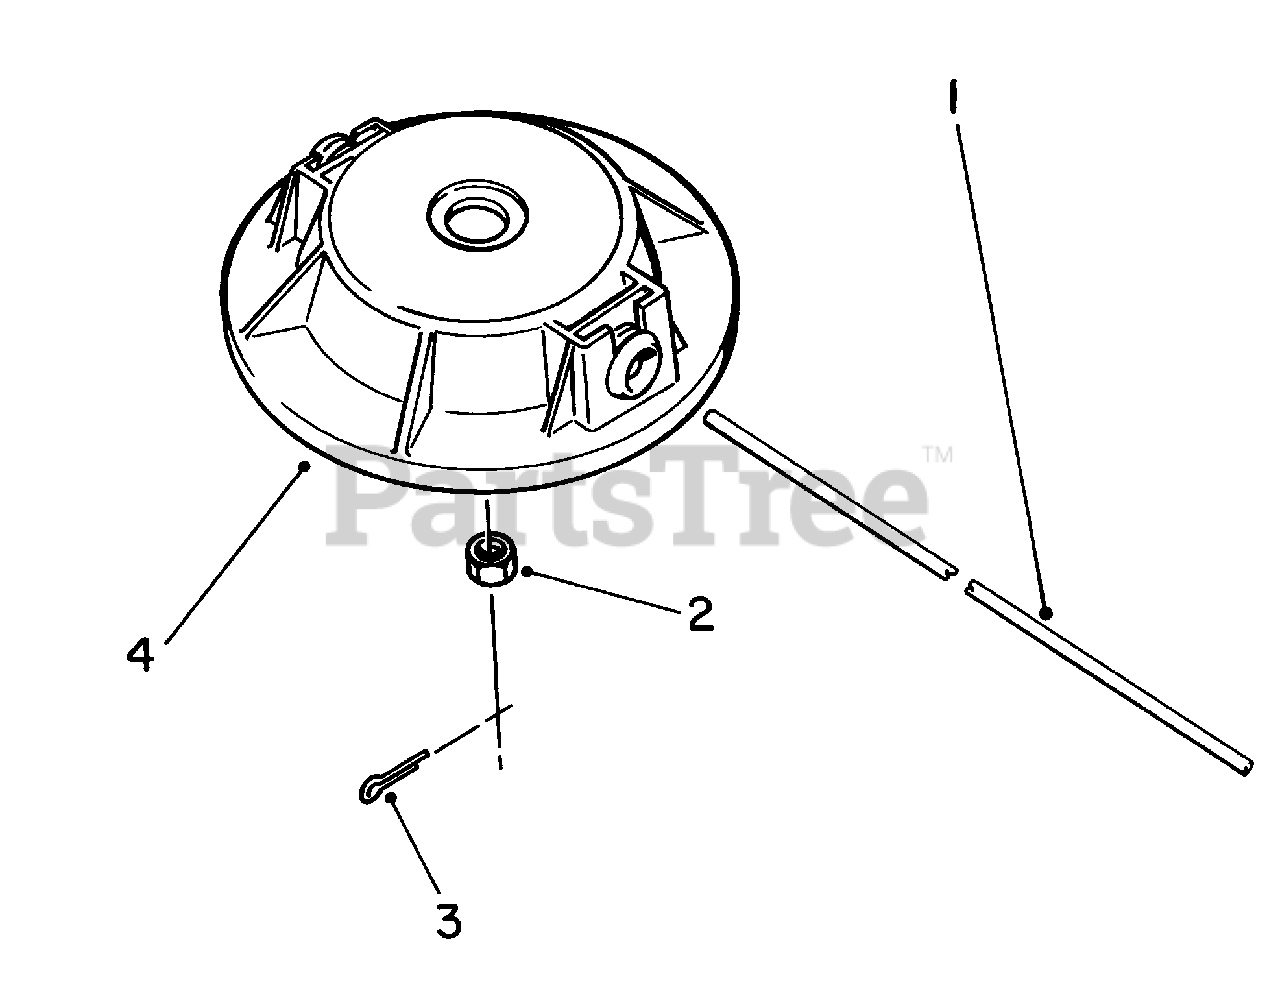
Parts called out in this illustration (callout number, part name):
1	.105 (100 Pcs.) (Optional)
3	Cotter Pin
4	Head Assembly
